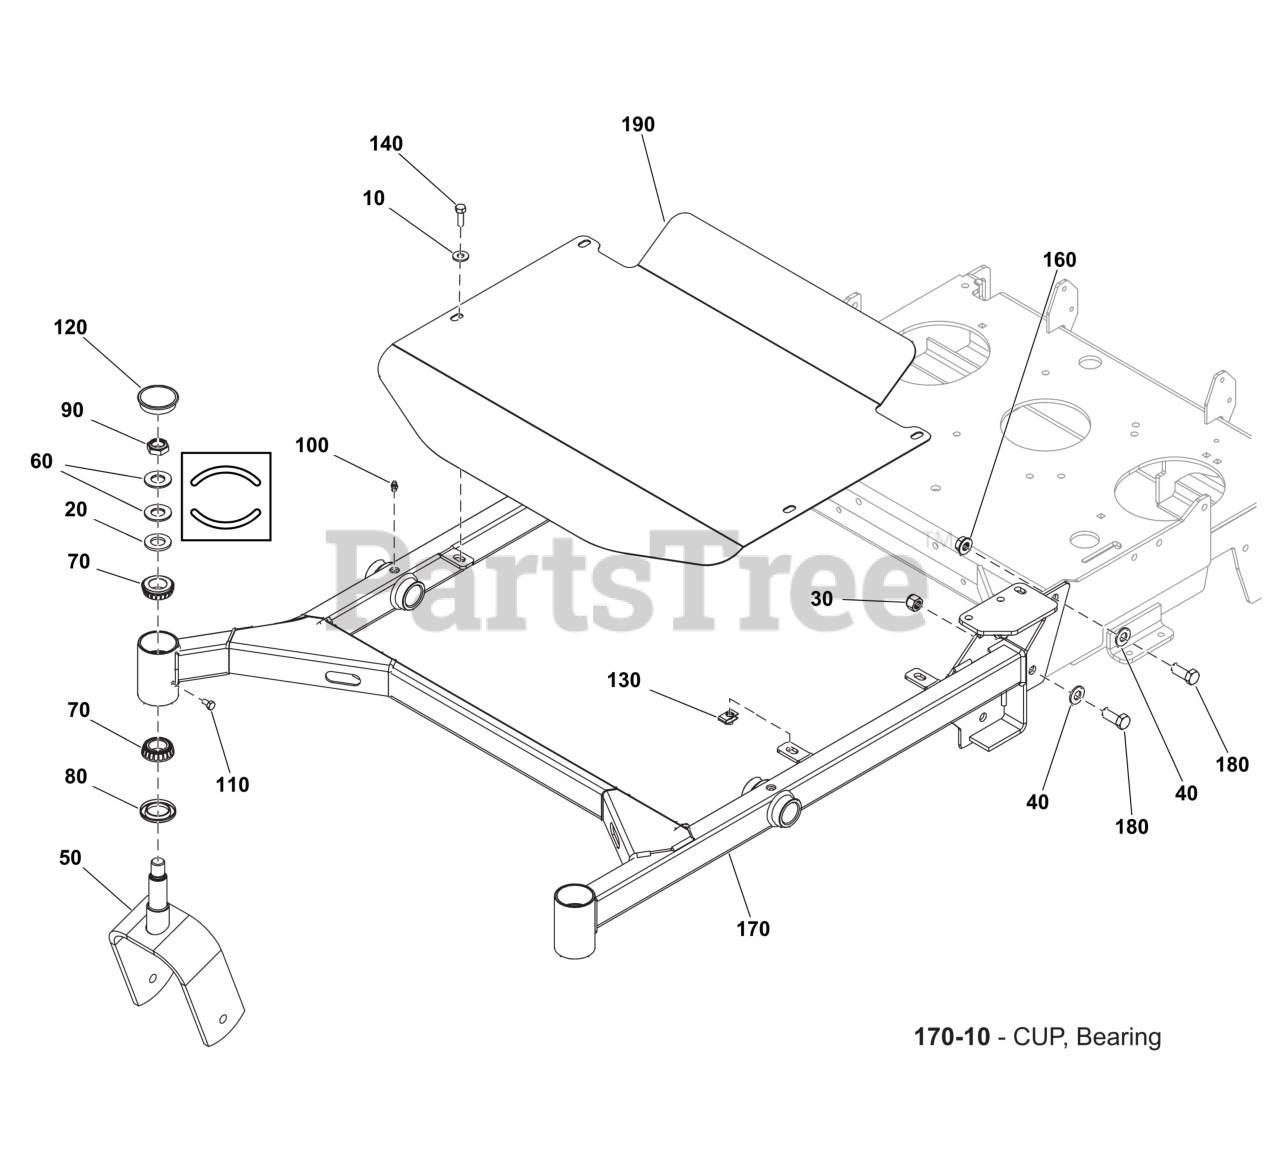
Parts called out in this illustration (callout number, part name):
20	WASHER, 3/4" SAE
40	WASHER, 1/2" SAE
50	YOKE, CASTER
60	WASHER, BELLEVILLE
70	BEARING, TAPERED ROLL
80	SEAL, GREASE
90	NUT - 3/4-16 HEX JAM
100	GREASE FITTING, 1/4-2
110	BOLT - 1/4-28 X 1/2
130	BODY CLIP, 5/16-18 X
170	FRAME, FRONT
170-10	CUP, BEARING (SV)
180	BOLT, 1/2-13 X 1-1/4
190	GUARD, Front
